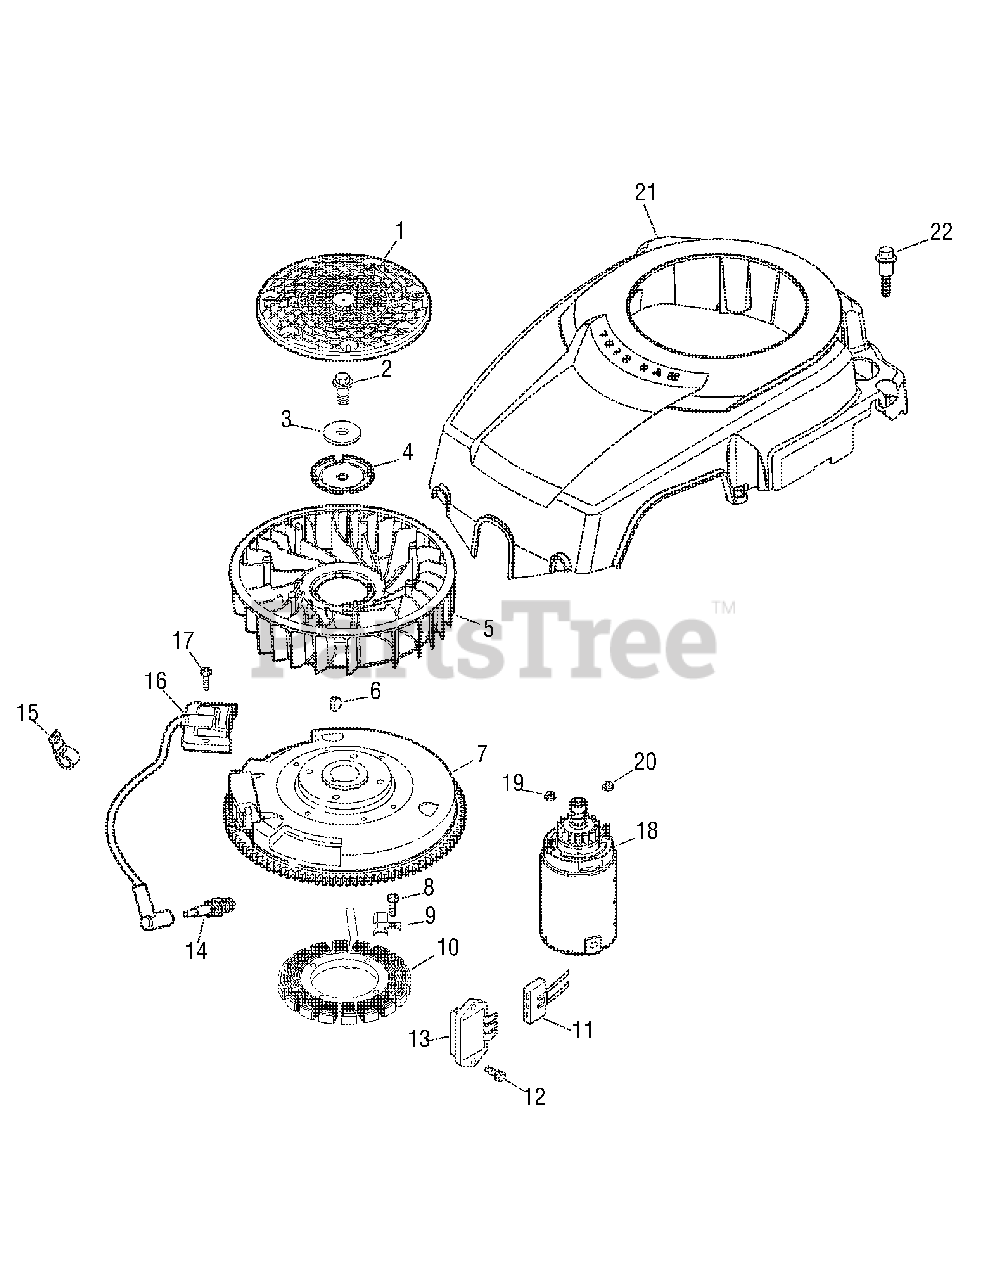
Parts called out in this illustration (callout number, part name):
1	Screen, grass
2	Screw, hex. flange M10 x 1.5 x 46
3	Washer, flat
4	Plate, fan mounting
6	Key, woodruff
7	Flywheel
8	Screw, hex. socket M5 x 0.8 x 25
10	Kit, stator
11	Connector, body (3 contact)
12	Screw, hex. flange M5 x 0.8 x 20
13	Rectifier-regulator
14	Plug, spark
15	Clip, cable
16	Module, ignition
17	Screw, hex. socket M5 x 0.8 x 25
18	Starter assembly, inertia drive
19	Nut, hex. serrated flange #10-24
20	Nut, hex. flange 1/4-20
21	Housing, blower
22	Screw, shoulder M5 x 0.8 x 36
